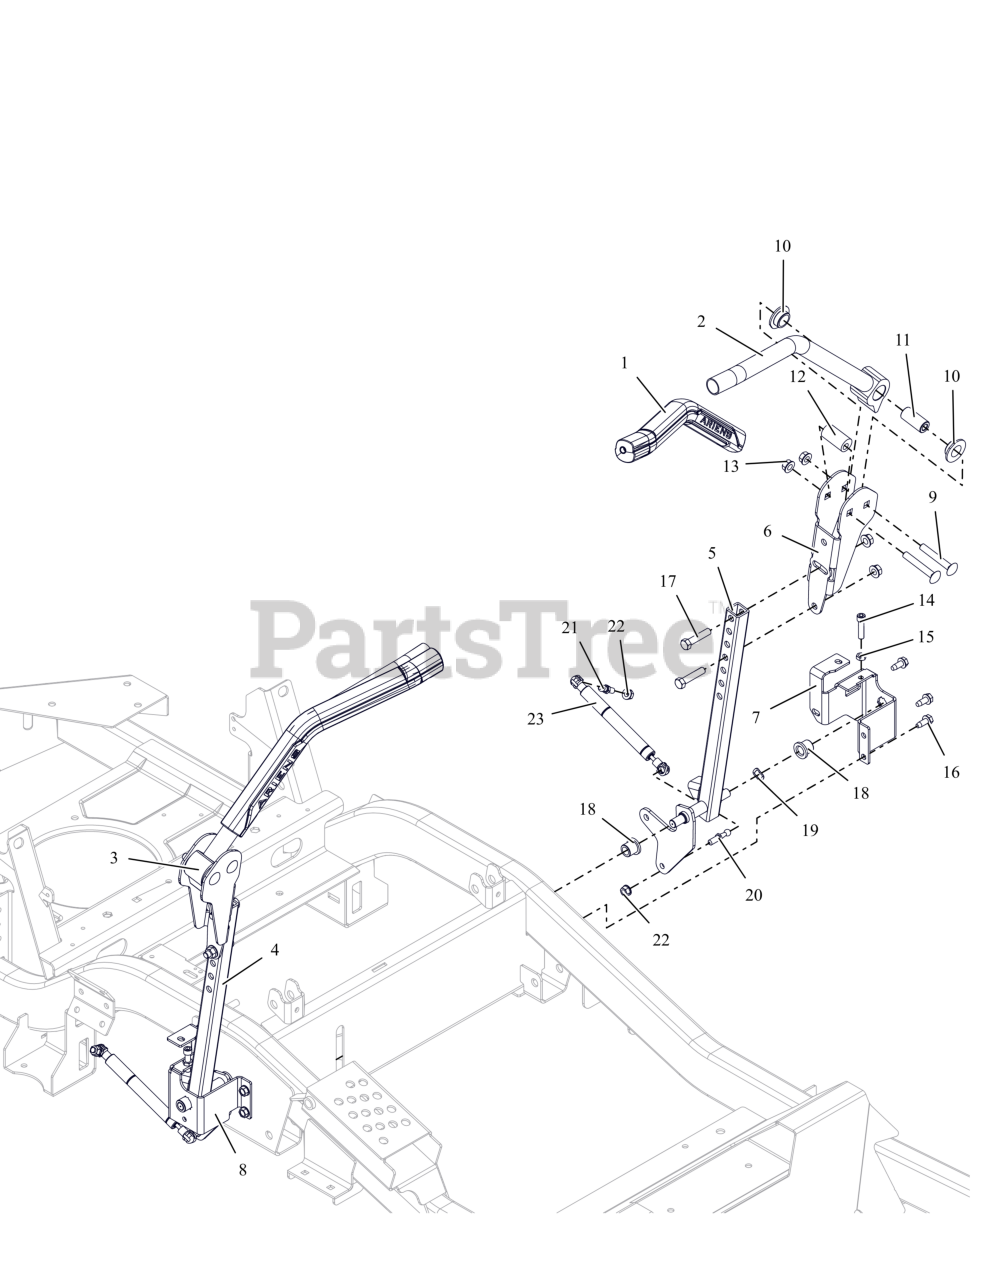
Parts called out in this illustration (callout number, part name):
1	GRIP- HANDLEBAR ARIENS
2	WLDMT, CONTROL HANDLE-LH (BLACK)
3	WLDMT, CONTROL HANDLE-RH (BLACK)
4	WLDMT, STEERING RH
5	WLDMT, STEERING LH
6	ADJ UPPER CONTROL ARM BRKT-BLK
7	BRKT, STEERING ARM MOUNT -LH
8	BRKT, STEERING ARM MOUNT -RH
9	BLT, RHSSN.38-16X2.50 G5 ZCC
10	BSHG-FLG .762X1.48X.44 IGLIDER
11	SPACER, STEERING ARM
12	BSHG, ECCENTRIC.406X.875X1.625
13	NUT-LK-TOP-FLG .38-16 ZC120
14	BLT, SHCS .312-18X1.25 G8 SS
15	NUT-JAM .312-18 G2 ZCC
16	SCR,TAP .312-18X.75 HWH TR ZCC
17	BLT, HEX .38-16X1.75 G5 ZCC
18	BHSG-FLG .500X.750X.750X.125
19	WAVE WASHER .531X.781X.125FH
20	STUD-BALL-THREADED
21	STUD- BALL
22	NUT,LK-CTR-FLG .31-18 GF ZCC
